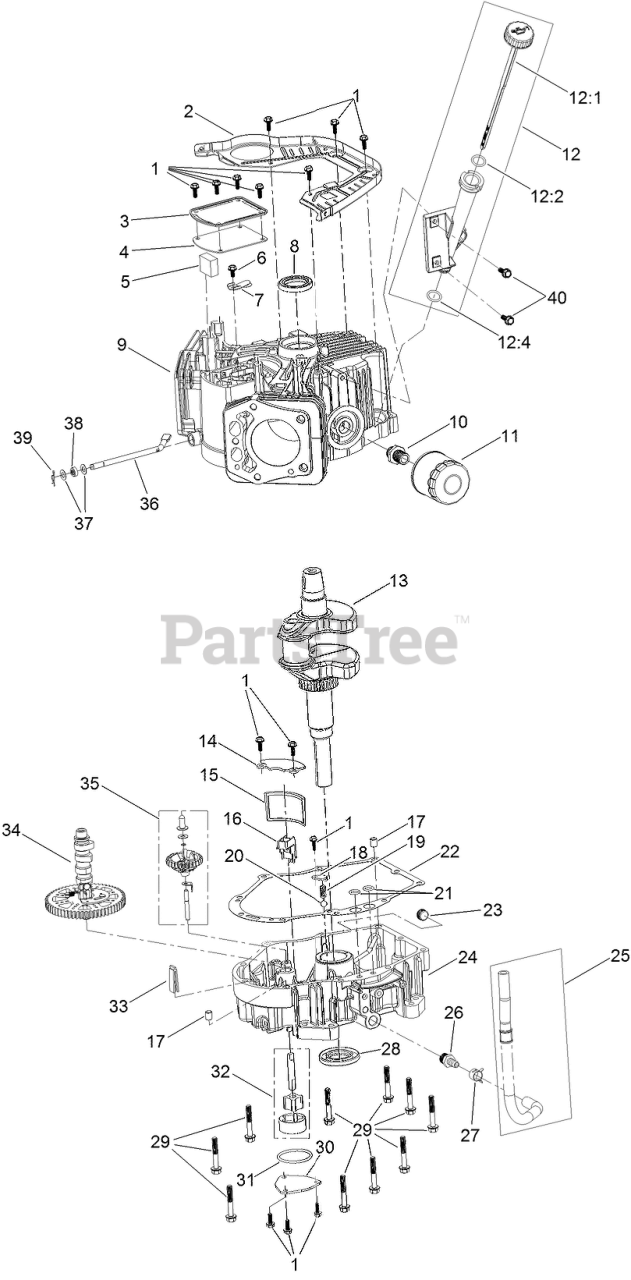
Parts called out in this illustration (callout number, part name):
1	SCREW-HHF
2	BAFFLE
3	COVER-BREATHER
4	GASKET-BREATHER
5	FILTER-BREATHER
6	SCREW-HHF
7	VALVE-BREATHER
8	SEAL-OIL
9	CRANKCASE
10	FITTING-THREADED, OIL FILTER
11	FILTER-OIL
12	OIL TUBE ASM
12:1	DIPSTICK
12:2	O-RING
12:4	O-RING
13	CRANKSHAFT
14	COVER-SCREEN, OIL
15	SCREEN-OIL
16	RETAINER-SCREEN
17	PIN-DOWEL
18	PLATE-RETAINER
19	SPRING
20	VALVE-BALL
21	O-RING
22	GASKET-COVER, CRANKCASE
23	PLUG-DRAIN
24	COVER-CRANKCASE
25	OIL DRAIN HOSE ASM
26	FITTING-HOSE
27	CLAMP-HOSE
29	SCREW-HHF
30	COVER-OIL PUMP
31	O-RING
32	OIL PUMP ASM
33	DEFLECTOR-OIL, RUBBER
34	CAMSHAFT
35	GOVERNOR ASM
36	ROD-GOVERNOR
37	WASHER-PLAIN
38	SEAL-OIL
39	PIN-HAIR
40	SCREW-HHF
